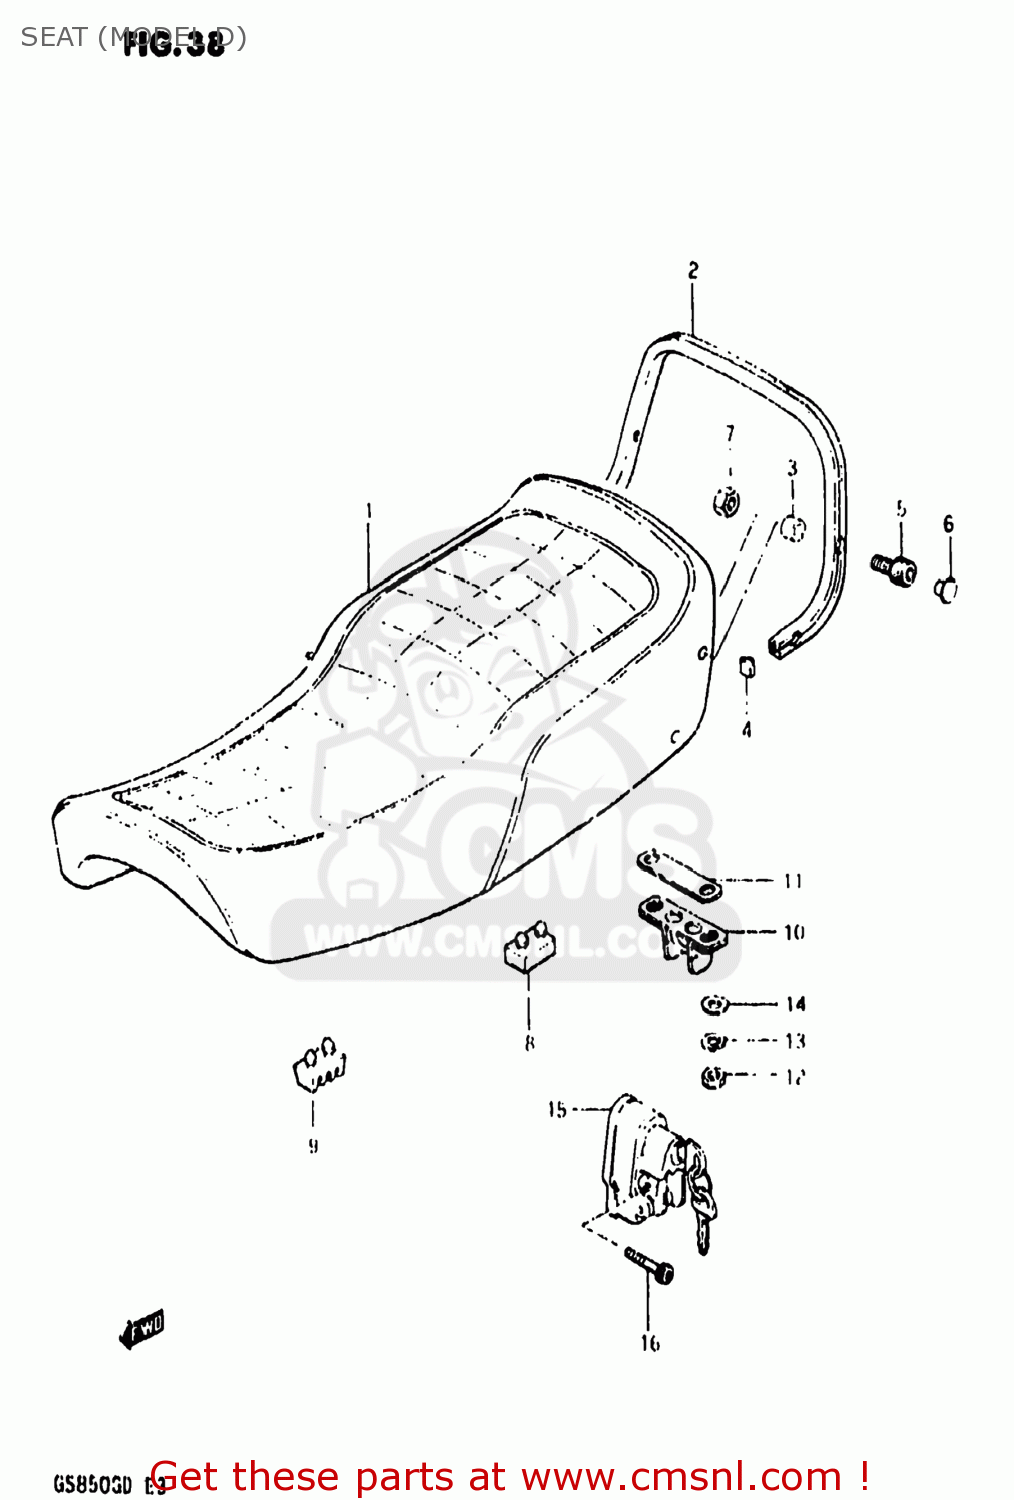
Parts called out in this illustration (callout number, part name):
1	SEAT ASSEMBLY
2	HANDLE,PILLION RIDER
3	SPACER,REAR
4	HANDLE,PILLION RIDER
5	BOLT
6	CAP(OD:14.5)
7	NUT
8	CUSHION(40X23X12.7)
9	CUSHION,SUPPORT(50X25X32)
10	STRIKER,SEAT LOCK
11	SHIM,SEAT LOCK STRIKER
12	NUT 6MM
13	LOCK WASHER
14	WASHER
15	LOCK ASSY,HELMET
16	BOLT 5X25
